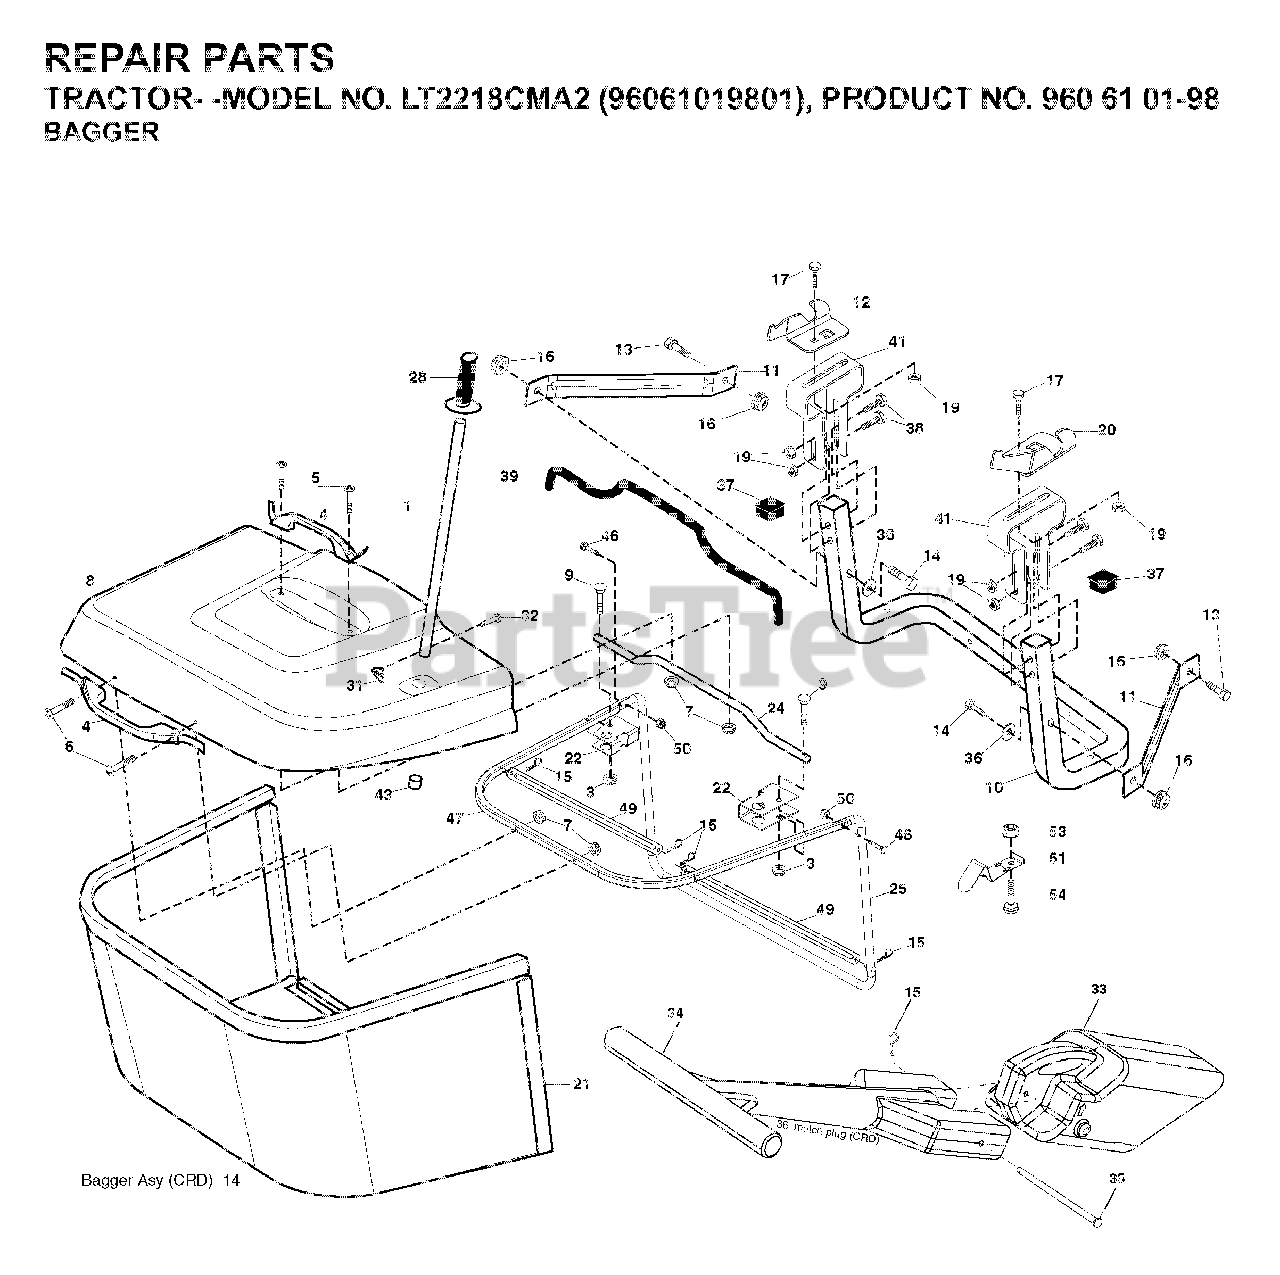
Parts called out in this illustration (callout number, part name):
1	TUBE HANDLE
3	NUT T
5	SCREW.PAN.HEAD
11	BRACKET
14	BOLT-HEX EAK
15	RETAINER-SPRNG RB
16	NUT LOCK FLG 3/8-16 UNC
17	BOLT
19	NUT LOCK HEX FLANGE 5/16-18
20	BRKT.PIVOT.RH.CRD
21	BAGGER.ASM.CRD.2007
22	BRACKET
24	TUBE
28	GRIP.HANDLE.BLACK
31	RETAINER CLIP
32	RIVET,DRILLED
33	MULCH PLUG, CTH150
35	PIN
38	BOLT.5/16-18X2.5
41	BRKT, BAGGER
43	PLUG, TUBING END
46	BOLT.CARRIAGE.5/16-18
50	NUT.71038.31-18.HEX.NYLOCK
53	NUT
54	BOLT
